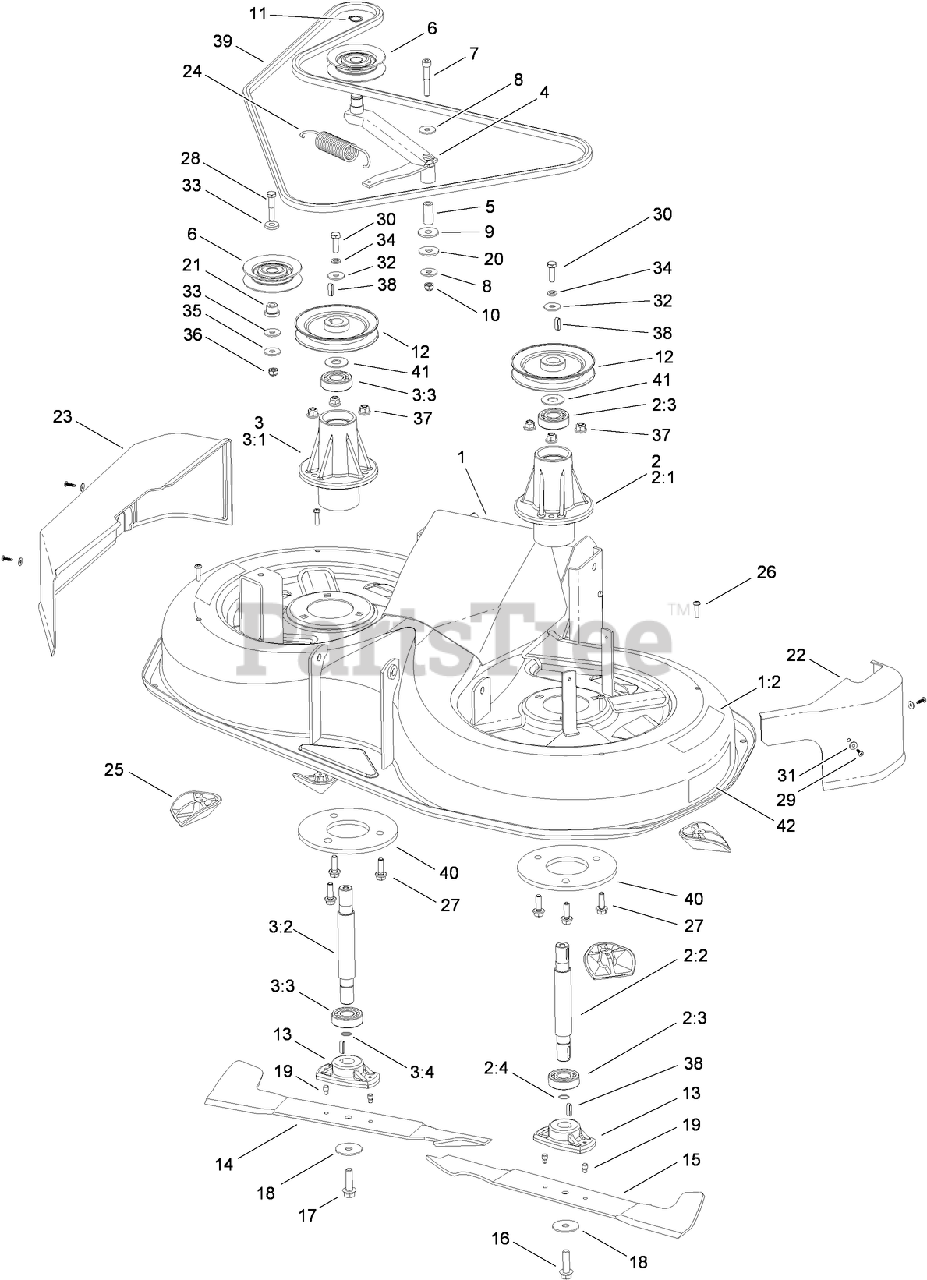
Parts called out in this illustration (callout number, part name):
1	DECK ASM
1:2	DECAL-DANGER
2	LEFT SPINDLE ASM
2:1	HOUSING-SPINDLE
2:2	SHAFT-BLADE, LEFT
2:3	BEARING
2:4	RING-LOCK
3	RIGHT SPINDLE ASM
3:1	HOUSING-SPINDLE
3:2	SHAFT-BLADE, RIGHT
3:3	BEARING
3:4	RING-LOCK
4	ARM-IDLER
5	SPACER
6	PULLEY-IDLER
7	BOLT-HH
8	WASHER-PLAIN
9	WASHER-PLAIN
10	NUT-LOCK, NI
11	RING-LOCK
12	PULLEY-MOWING BELT, 4.5IN
13	ADAPTER-MOUNT, BLADE
14	BLADE-RH
15	BLADE-LH
16	SCREW-HEX
17	SCREW-HH, LEFT
18	WASHER-BELLEVILLE
19	PIN-SHEAR, GROOVED
20	WASHER
21	BUSHING
22	GUARD-BELT, LEFT
23	GUARD-BELT, RIGHT
24	SPRING
25	KICKER
27	SCREW-HHF
28	SCREW-HH
30	SCREW-HH
31	WASHER
32	WASHER
33	Washer-Flat
34	WASHER-SPRING
35	WASHER-PLAIN
36	NUT-LOCK, NI
37	NUT-LOCK, HHF
39	BELT-WEDGE, DOUBLE
40	SUPPORT-RING
41	WASHER-PLAIN
42	DECAL-RECYCLER
